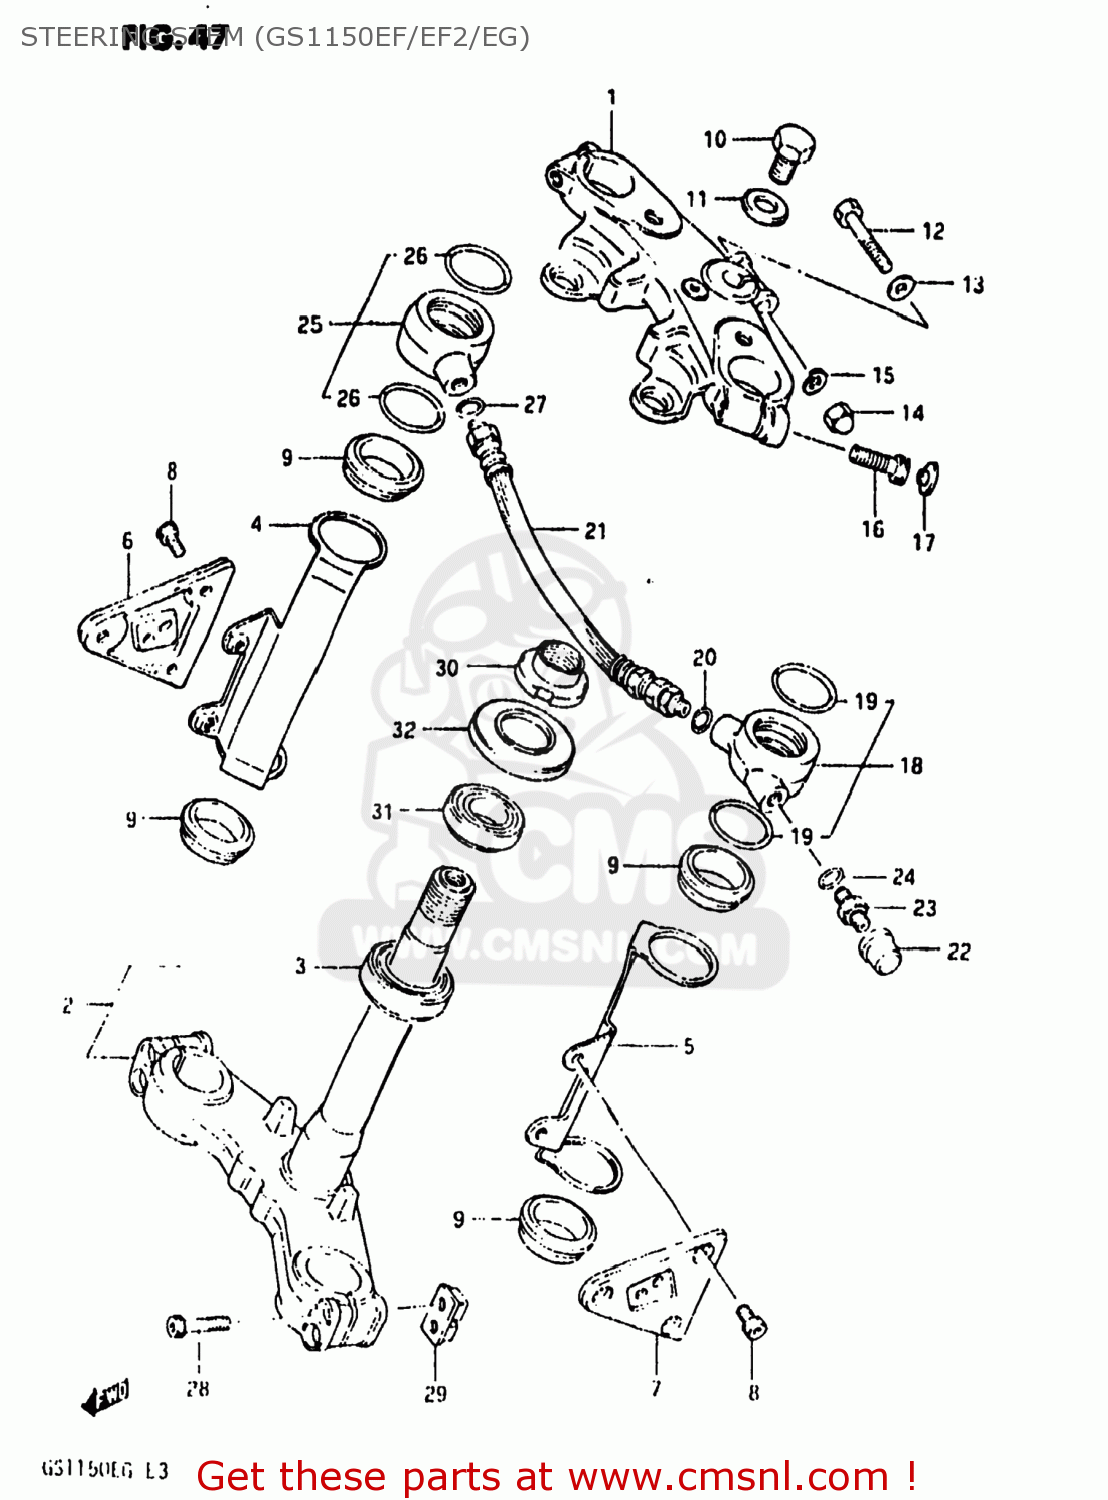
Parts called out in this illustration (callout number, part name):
1	HEAD,STEERING STEM
2	STEM,STEERING
3	BEARING
4	BRACKET COMP,HEADLAMP
5	BRACKET COMP,HEADLAMP
6	BRACKET,HEADLAMP,RIGHT N
7	BRACKET,HEADLAMP,LEFT N
8	BOLT
9	CUSHION,HEADLAMP BRACKET
10	NUT,STEM HEAD
11	WASHER,STEERING STEM
12	BOLT
13	WASHER
14	NUT,M8X1.25X12
15	WASHER,LOCK,8.
16	BOLT,FORK INNER TUBE FITTING
17	CAP(OD:20)
18	JOINT,AIR,LEFT
19	O RING
20	O-RING
21	JOINT,AIR TUBE
22	CAP,FRONT FORK AIR VALVE
23	VALVE,FRONT FORK AIR
24	O-RING
25	JOINT,AIR,RIGHT
26	O RING
27	O-RING
28	BOLT 8X45
29	NUT,FR FORK INNER TUBE
30	NUT,STEERING STEM
31	TAPER,ROLLER BEARING
32	DUST SEAL,STEERING UPR
